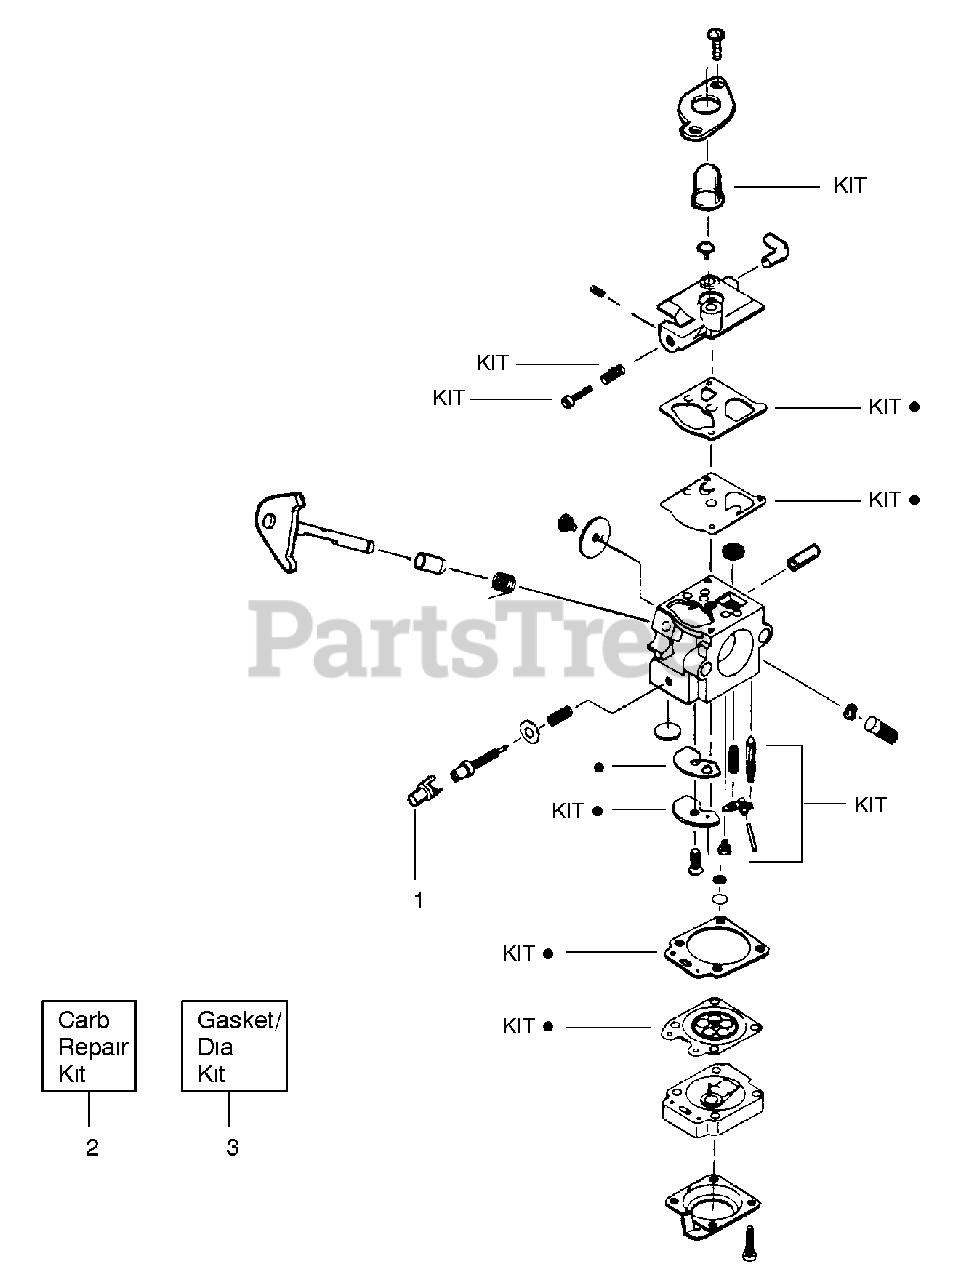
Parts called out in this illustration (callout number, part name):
1	Limiter Cap
2	Carburetor Repair Kit
3	Gasket Diaphragm Kit
